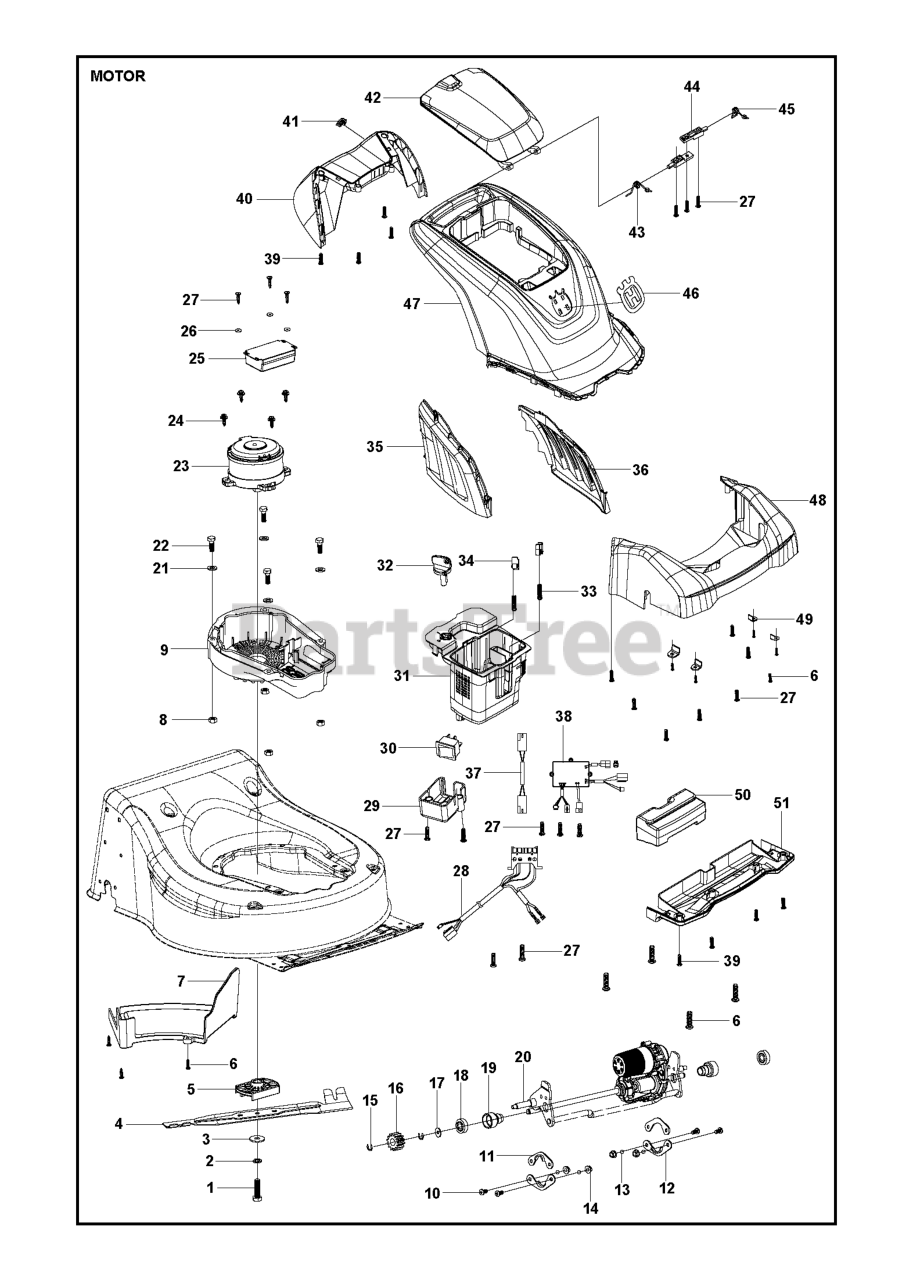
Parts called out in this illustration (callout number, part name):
2	SPRING WASHER
4	MOWER BLADE MULCH 40CM PRODUCT
5	BLADE SUPPORT
7	COVER LOW PROTECT # 2106100379
8	NUT LOCKING
10	SCREW M6*16 #26800204601
11	FIXING PLATE #26300314601
12	FIXING PLATE #26300124401
13	O-RING #25100175201
14	LOCK NUT M6,GB/T6187.1-2000 #2
15	WASHER Ï?9,GB896 #26800900201
16	GEAR #26900215601
17	WASHER Ï?12.8*Ï?20*0.8 #268007
19	BEARING HOUSING #26900211501
20	GEARBOX ASSY #23050206401
28	WIRE BATTERY CONNECTOR
30	KEY SWITCH
31	BOX BATTERY BOX
34	CAP COMPRESSION SPRING CAP
35	COVER RIGHT AIR WINDOW PLATE
36	COVER LEFT AIR WINDOW PLATE
37	LINE CONNECTING # 27100124701
38	PRINTED CIRCUIT ASSY SEL-PROPE
40	COVER BACK COVER
42	COVER BATTERY LID
43	TORSION SPRING
44	HINGE BATTERY LID HINGE
45	TORSION SPRING LEFT
46	DECAL LOGO
47	COVER MOTOR COVER
48	COVER FRONT COVER
50	WEIGHT # 25100184101
51	COVER FRONT HANDLE (UNDER SIDE
